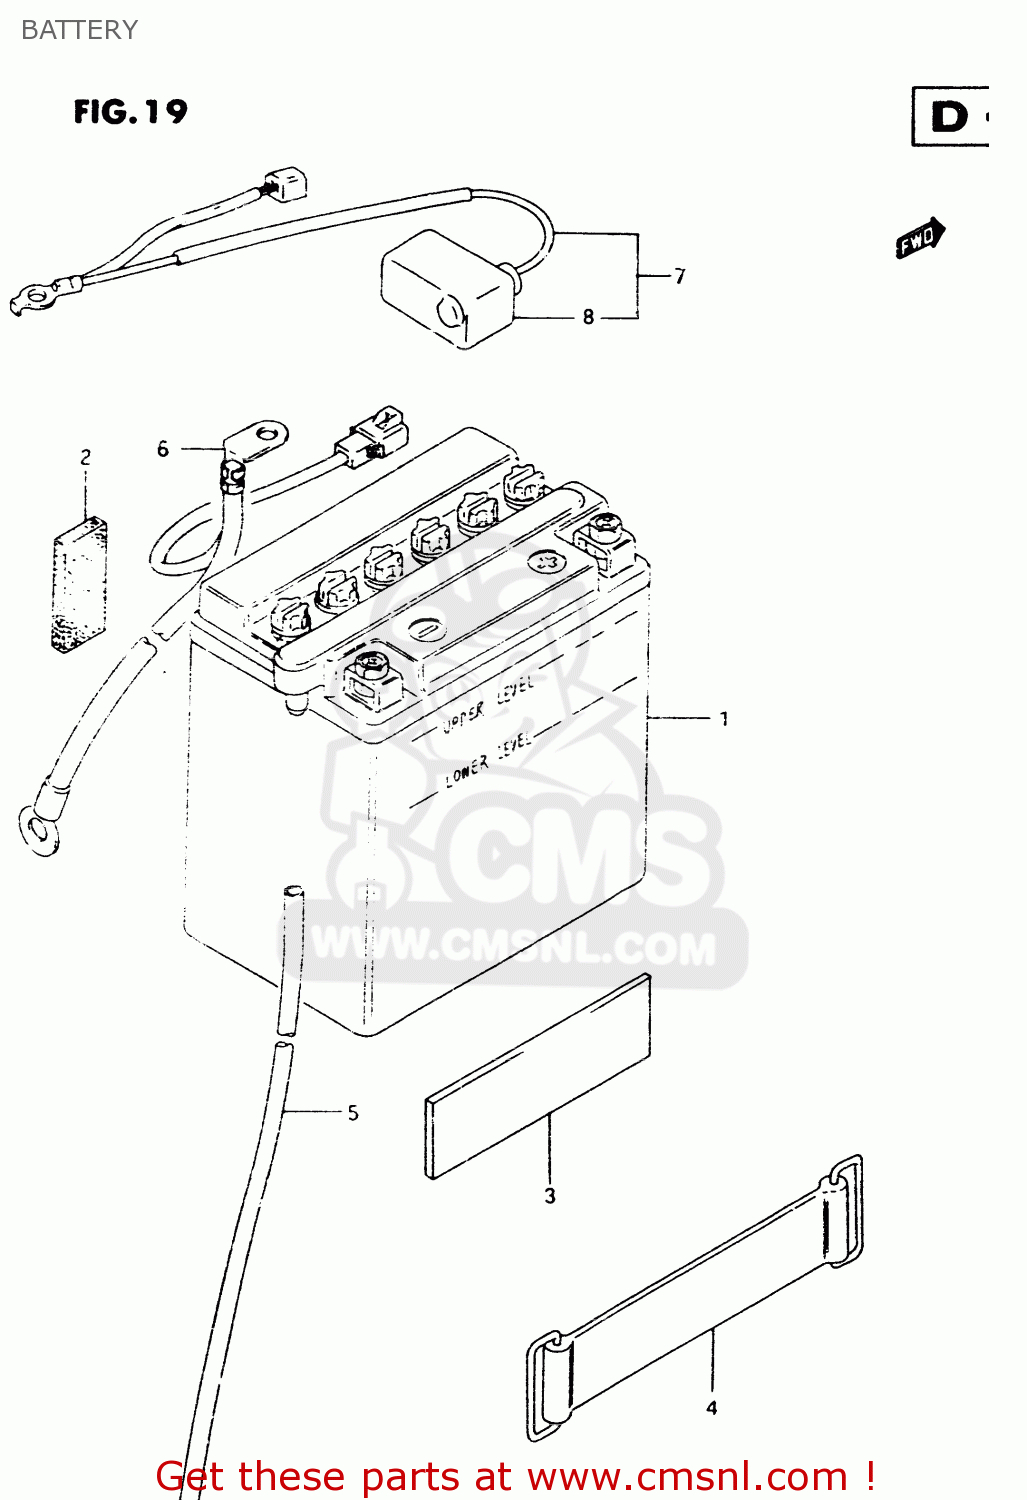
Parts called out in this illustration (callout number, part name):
1	BATTERY ASSY (12V)
2	CUSHION 20X45X6
3	PROTECTOR(170X95X3.0)
4	BAND
5	HOSE,BATTERY EXHAUST(L:780)
6	WIRE,BATTERY MINUS LEAD
7	WIRE, BATTERY (+) LEAD
8	CAP,BATTERY PLUS TERMINAL
